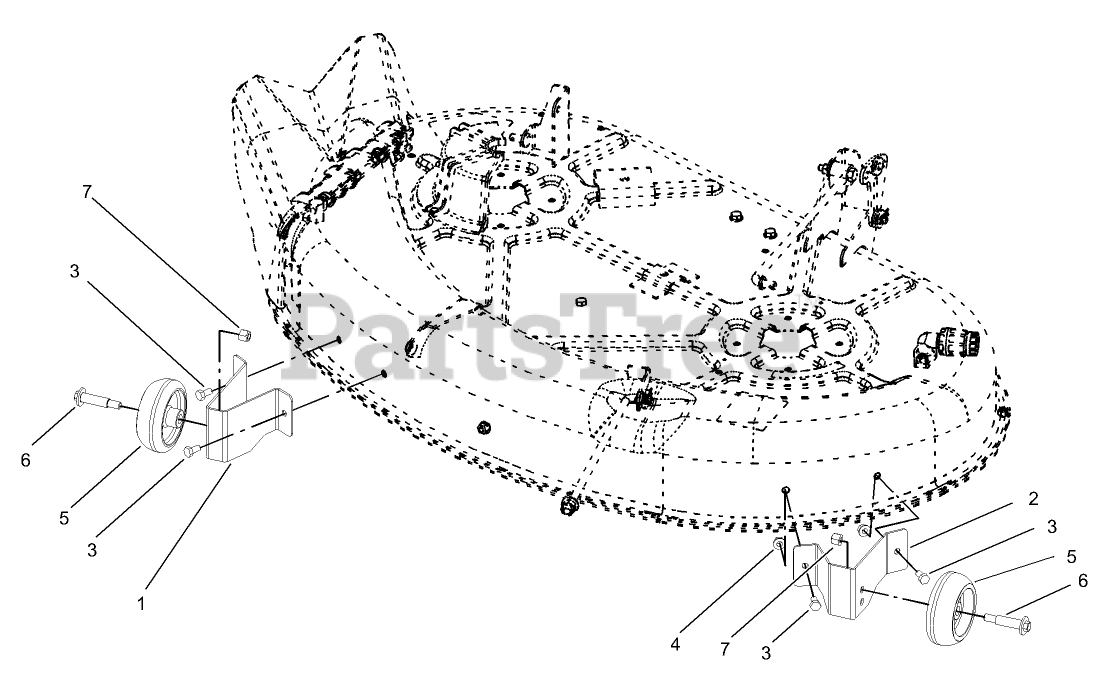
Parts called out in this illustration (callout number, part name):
1	BRACKET - GAGE WHEEL, FRONT RH
2	BRACKET - GAGE WHEEL, FRONT LH
3	SCREW-HH
4	NUT-HF
5	WHEEL-GAGE
6	SCREW-SHOULDER, HWH
7	NUT-LOCK, NI
